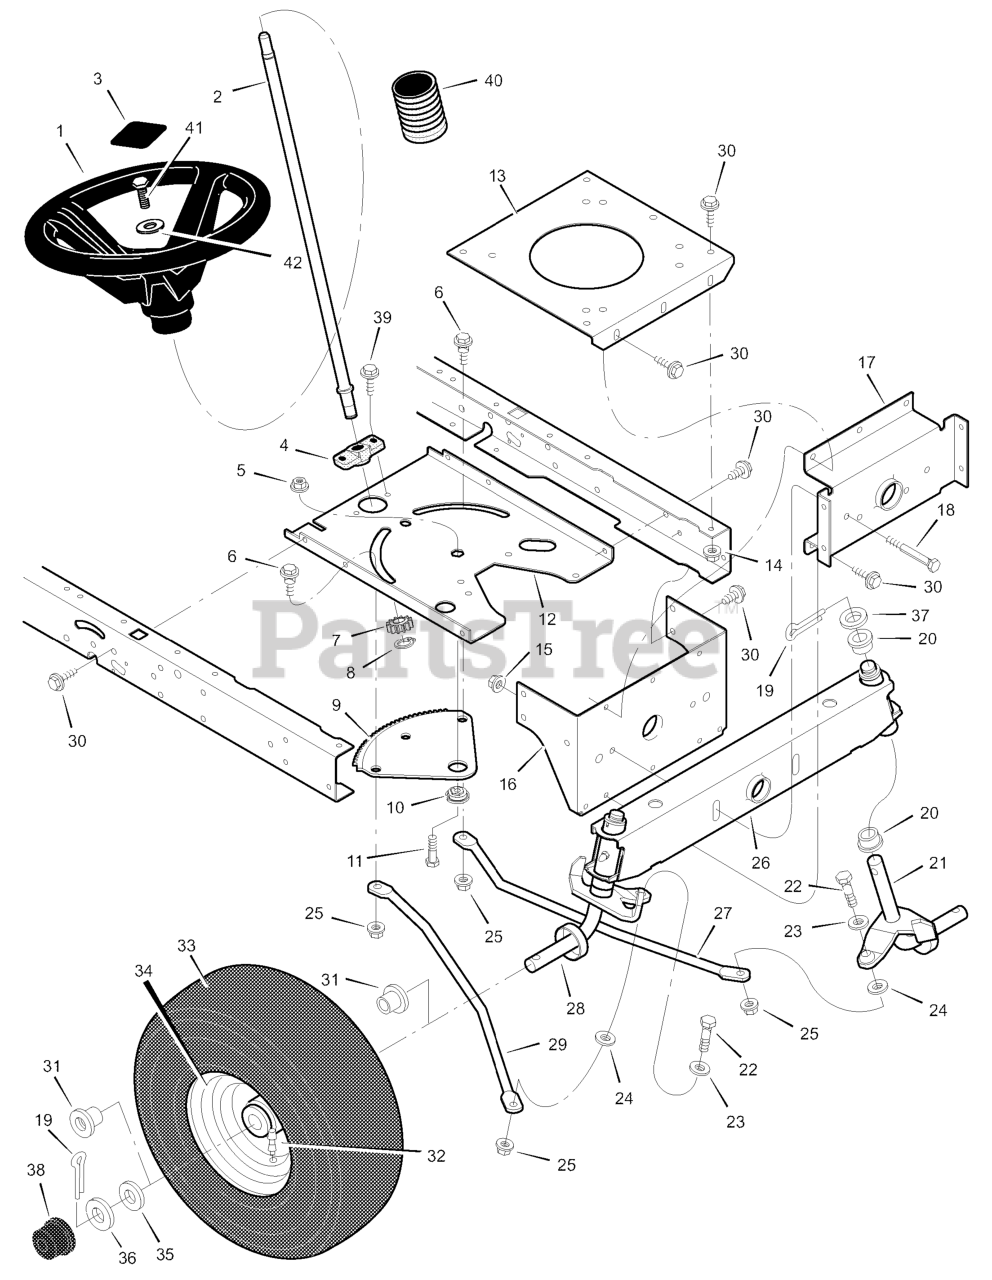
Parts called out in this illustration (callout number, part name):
1	Wheel, Steering
2	Post, Steering
3	Insert, Steering Wheel
4	Bearing
5	Nut, Flange
6	Bolt, Shoulder
7	Gear, Pinion
8	Ring, Snap
9	Gear, Sector
10	Bearing
11	CAPSCREW, Hex Head, 5/16-18 x 1
12	Plate, Steering
13	Plate, Engine
14	Nut, Flange
15	Nut, Flange
16	Bracket, Hanger
17	Axle, Hanger
19	Pin, Cotter
20	Bearing
21	Spindle Assembly, Left
22	Bolt
23	Washer
25	Nut, Flange
26	Axle Assembly
27	Drag Link, Left
28	Spindle Assembly, Right
29	Drag Link, Right
31	Bearing, Wheel
32	Stem, Valve
33	Tire *
34	Wheel and Tire Assembly
37	Washer
38	Hub Cap
40	Bellows
41	Screw, Hex
42	Washer
